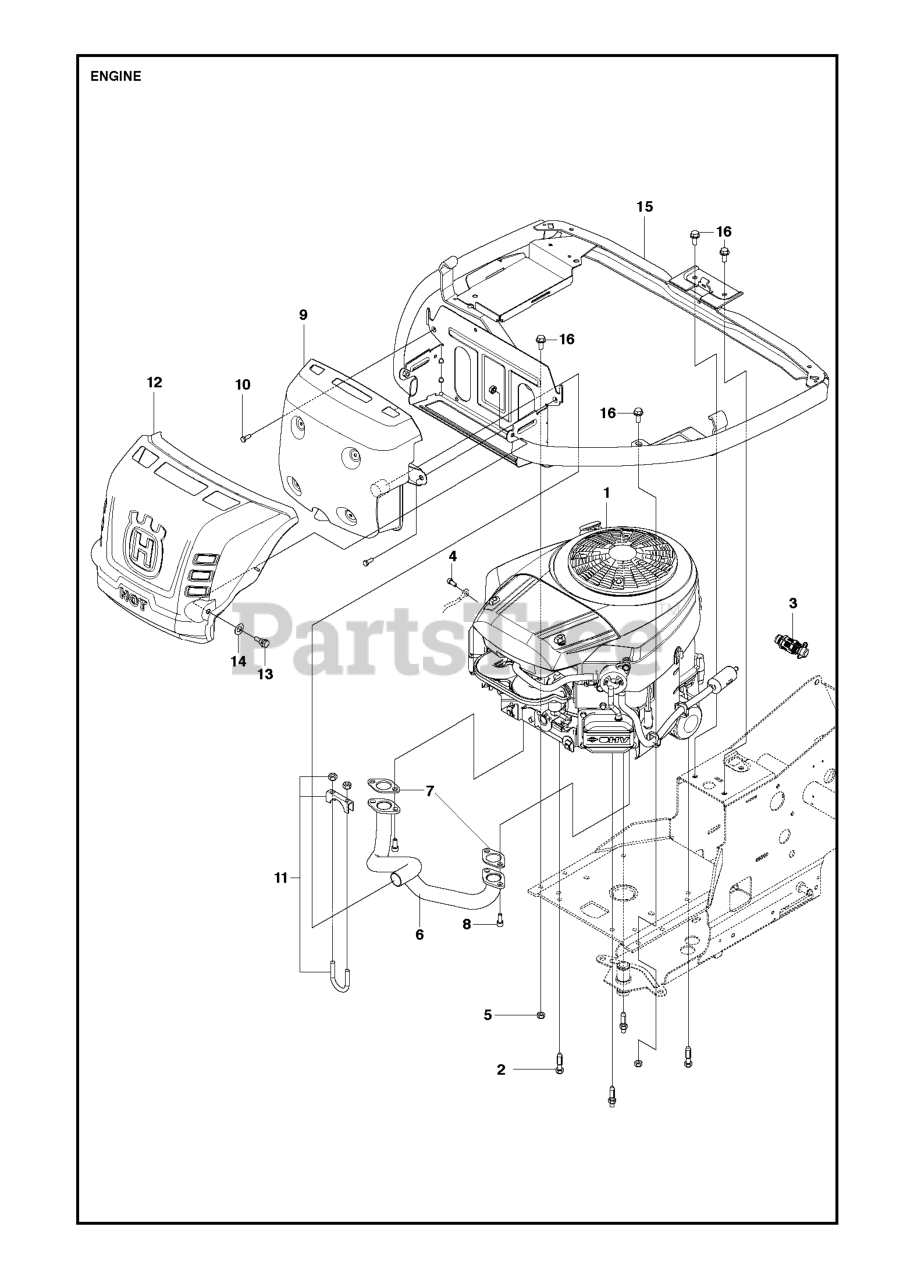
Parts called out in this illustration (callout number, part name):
2	STUD SCREW
3	VALUE.OIL.DRAIN
5	LOCKNUT M8
11	CLAMP
12	HEAT SHIELD
14	SPRINGWASHER
15	ENGINE FRAME
